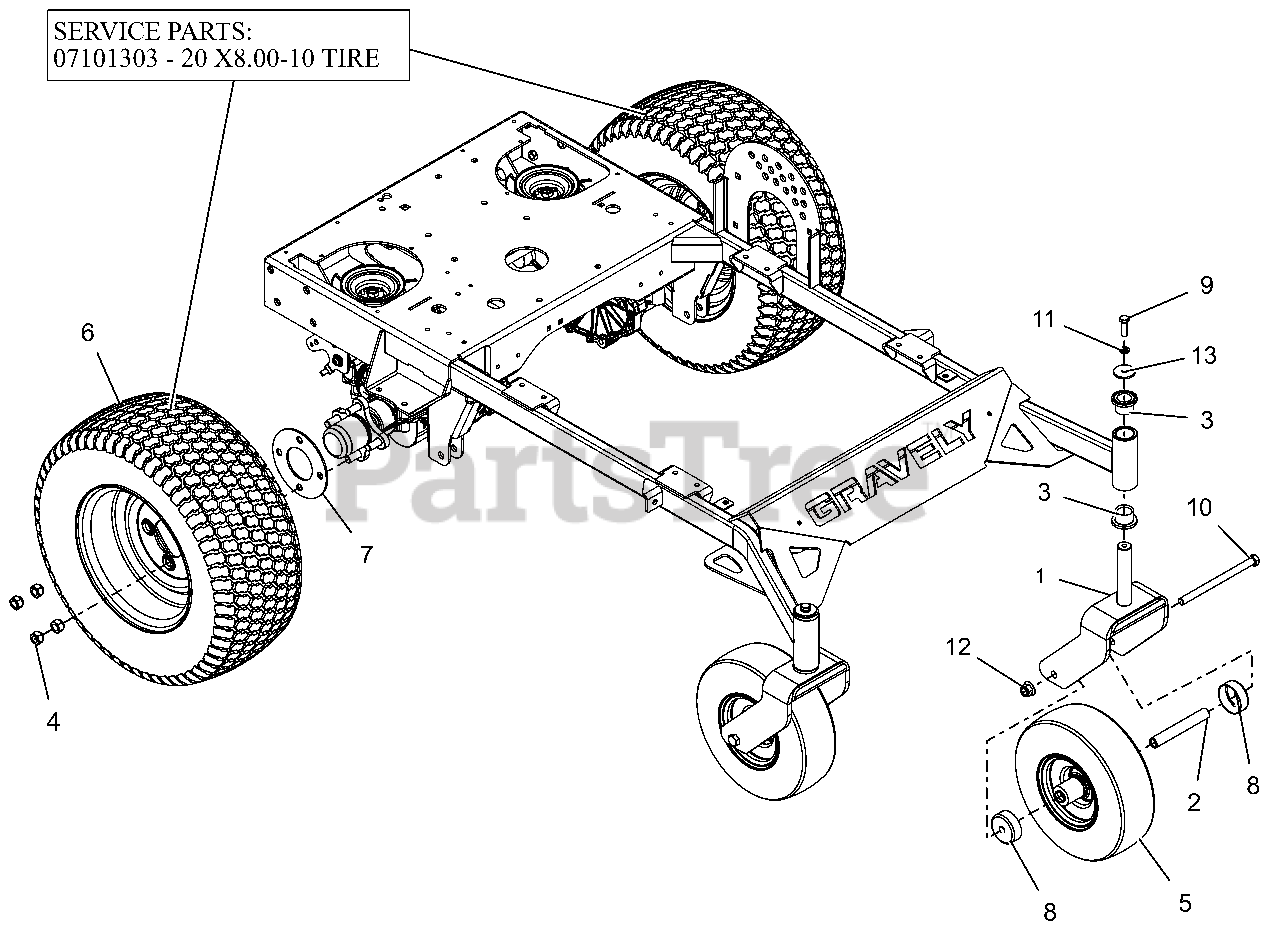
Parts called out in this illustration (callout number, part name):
1	WLDMT, CASTER FORK (RED)
2	SPACER, ROLLED WHEEL
3	BRG, FLG 1.00 X 1.25 X 1.00
4	WHEEL NUT .500-20 YZ
5	ASM, WHL/TIRE 11X4.00-5
6	ASM, WHL/TIRE 20X8.00-10
6	20 X 8.00-10 TIRE
7	SPACER, WHEEL 4-BOLT
8	SHIELD, WHEEL BEARING
9	@BLT-HEX .38-16X1.25 GR5 YWZC
10	@BLT-HEX .50-13X7.00 GR5 YWZC
11	@WSHR-LK .38X.094 REG YWZC
12	@NUT-LK-NYL-FLG .50-13 YWZC
13	WSHR-FL-STL .380X1.50X.125YWZC
